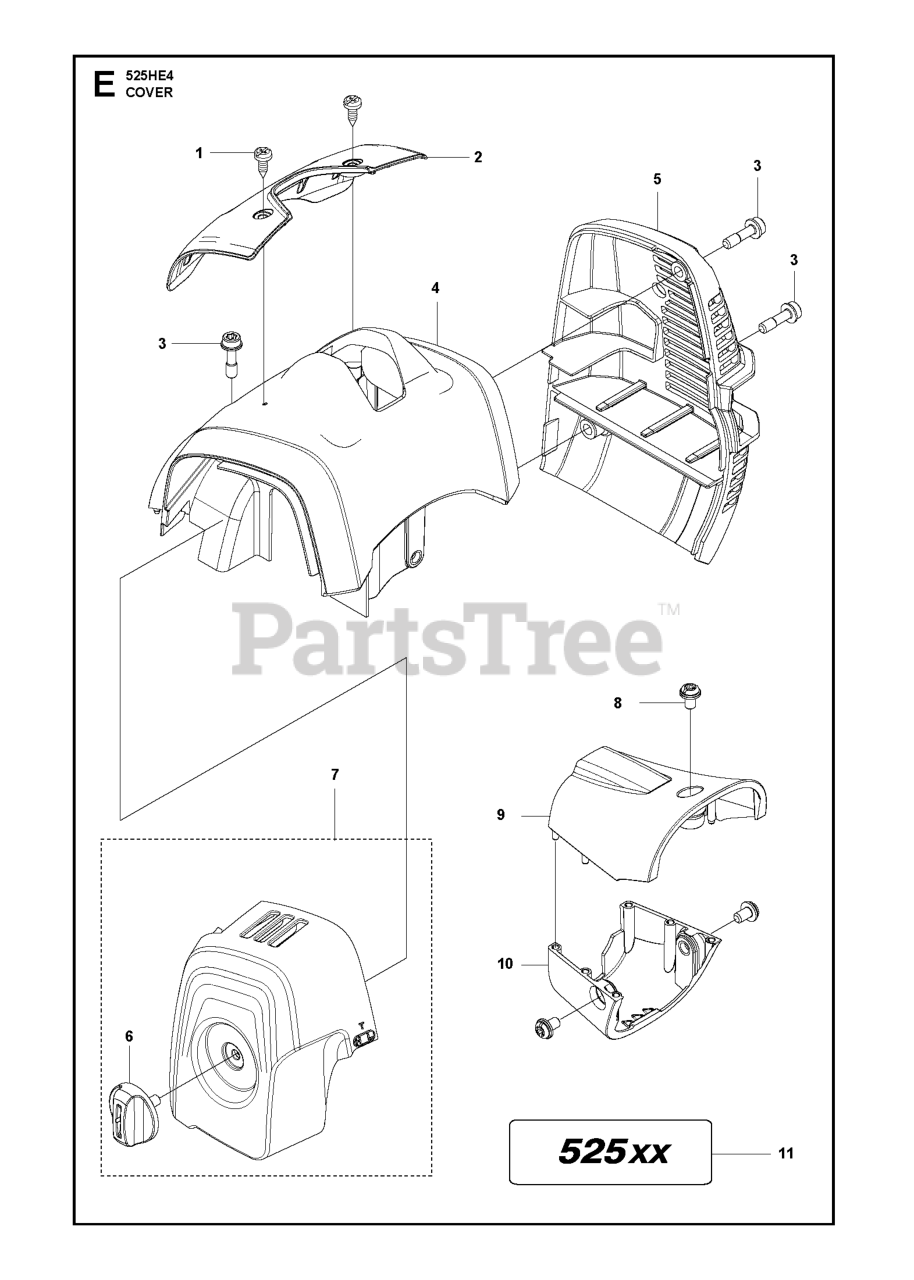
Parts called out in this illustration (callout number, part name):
2	ARM PROTECTION
3	BOLT
4	CYLINDER COVER
5	MUFFLER GUARD
6	KNOB CLEANER COLOR:GREY
7	FILTER COVER ASSY
9	COVER CLUTCH HOUSING,UPPER
10	COVER CLUTCH HOUSING,LOWER
